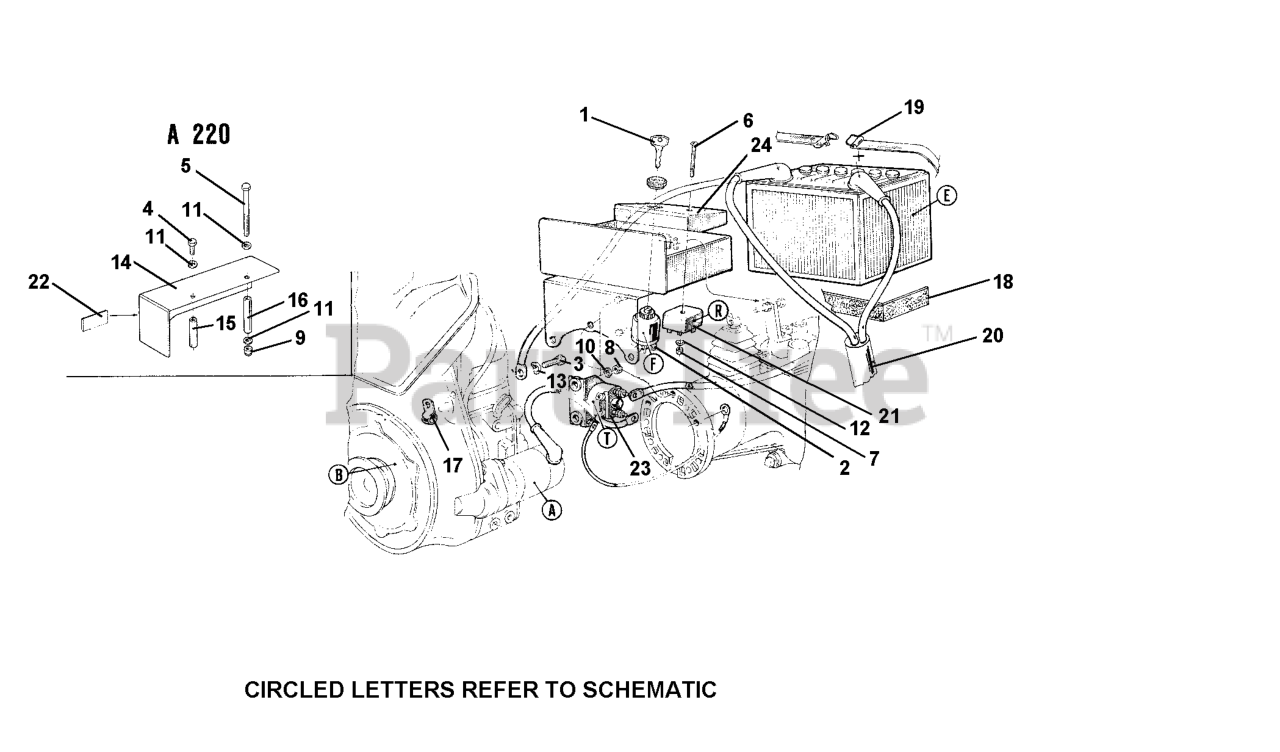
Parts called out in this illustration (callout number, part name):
3	SCREW M8 X 16
4	SCREW M6 X 12
5	SCREW TE M6 X 65
6	SCREW TC M4 X 30 UNI 6107
9	NUT, SELF LOCKING M6
10	WASHER, FLAT 6.4
11	WASHER, LOCK 6.4
12	LOCK WASHER B 4.3
13	WASHER, LOCK 8.4
14	STOP SWITCH PROTECTION
16	PROTECTION SPACER
17	SUPPORT, ACCELERATOR CABLE
18	SHOCK-PROOF RUBBER
19	BATTERY STRAP
20	ELEC. START CABLES MC 715
22	CHOKE DECAL
23	BOSCH RELAY 0332002160
24	BATTERY SUPPORT COMPL.
